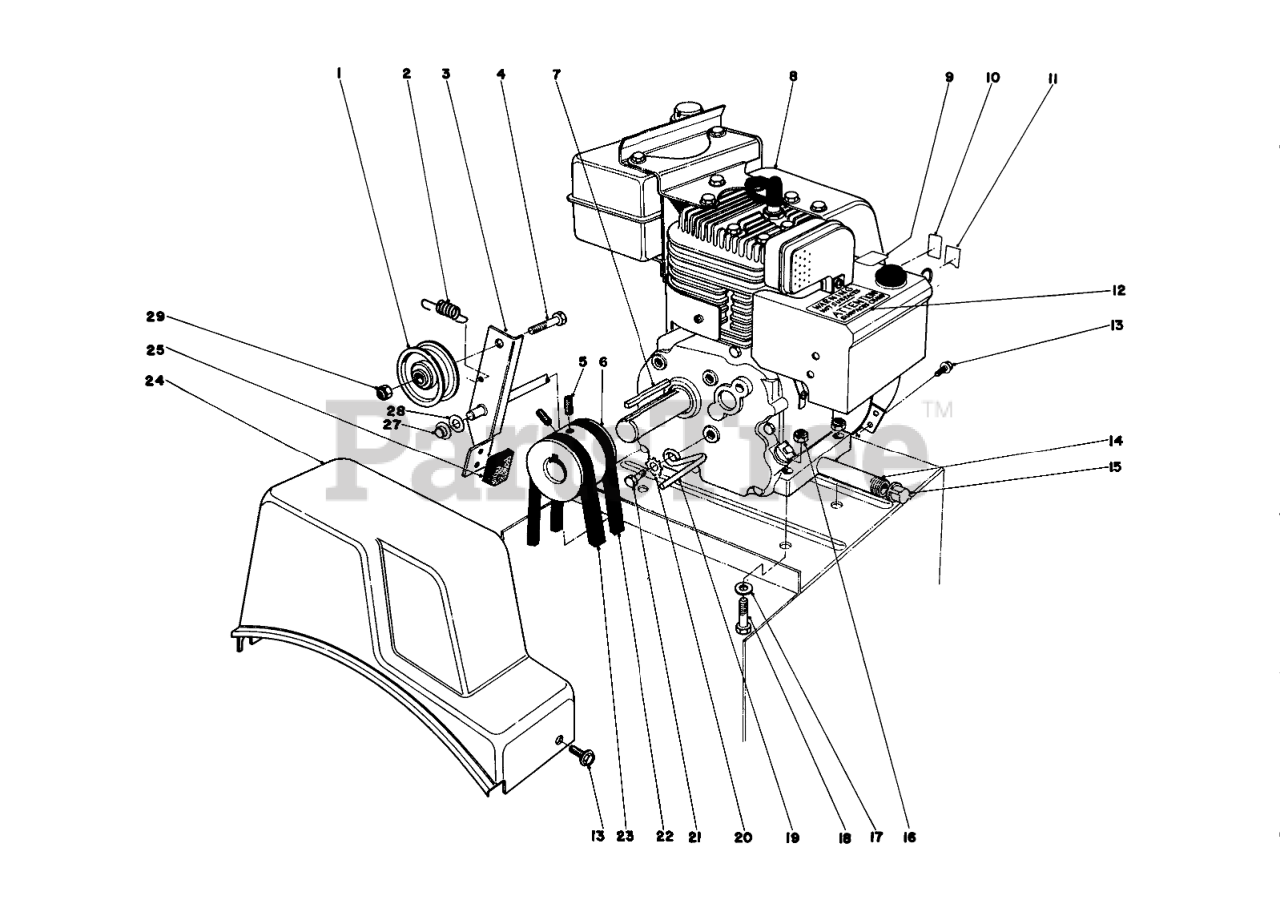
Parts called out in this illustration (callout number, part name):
1	PULLEY-IDLER
2	EXTENSION SPRING
3	Auger Clutch (Incl. Ref. #25)
4	SCREW-HH
5	Screw-Set
6	ENGINE PULLEY
8	Engine
9	PRIMER DECAL
10	DECAL THROTTLE
11	CHOKE DECAL
12	Decal Hot Surface Warning
13	SCREW
14	PIPE NIPPLE
15	CAP-PIPE
16	NUT-LOCK, NI
17	WASHER-PLAIN
18	SCREW-HH
19	RETAINER-BELT
20	WASHER-LOCK
21	SCREW-HH
22	V BELT-3L, TRACTION
23	V-BELT (29.50 INCH)
24	COVER-BELT
25	Brake Pad & Cushion Assy.
27	RETAINER-PUSH ON
28	WASHER-FLAT
29	NUT-LOCK, CONE
